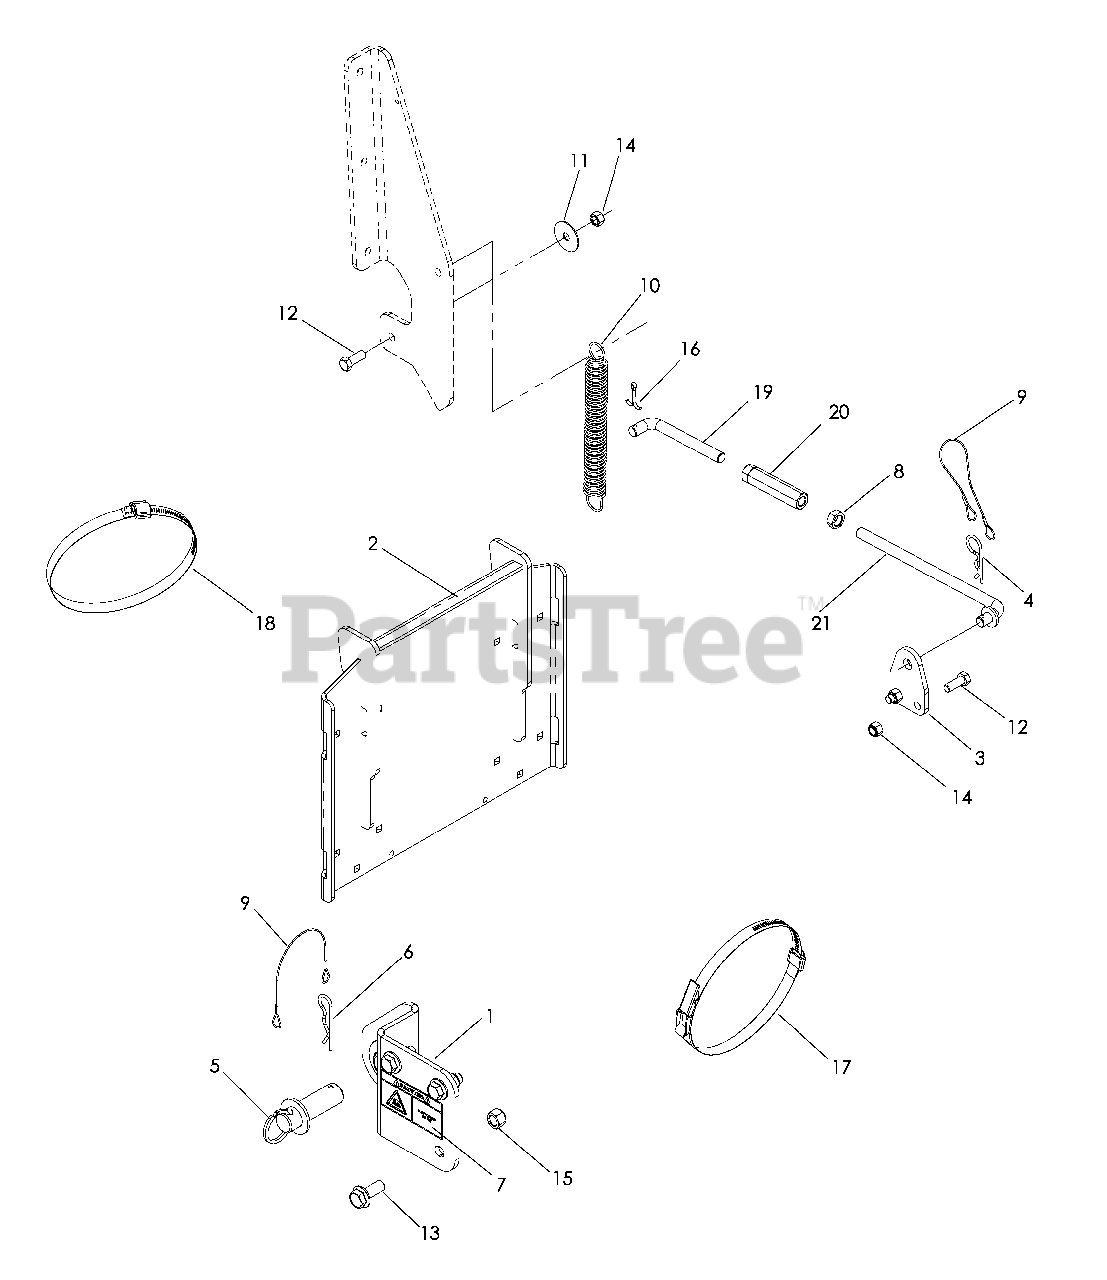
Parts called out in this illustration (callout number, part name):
1	HITCH BRACKET, RT W/DECAL
2	HITCH BRACKET, LT
3	REAR GUARD
4	SUPPORT BRACKET
5	HAIRPIN #4
8	DECAL, HOT SURFACE
9	NUT ½-20 HEX JAM
12	FRICTION WASHER
13	HCS 3/8-16 x 1
14	HFS ½-13 x 1½
15	NUT 3/8-16 NYLOC
16	NUT ½-13 NYLOC
17	COTTER PIN 5/32 x 1¼
18	OVER CENTER BAND
19	HOSE CLAMP
20	SUPPORT LINKAGE, LH
21	TURNBUCKLE ½"
22	SUPPORT LINKAGE
